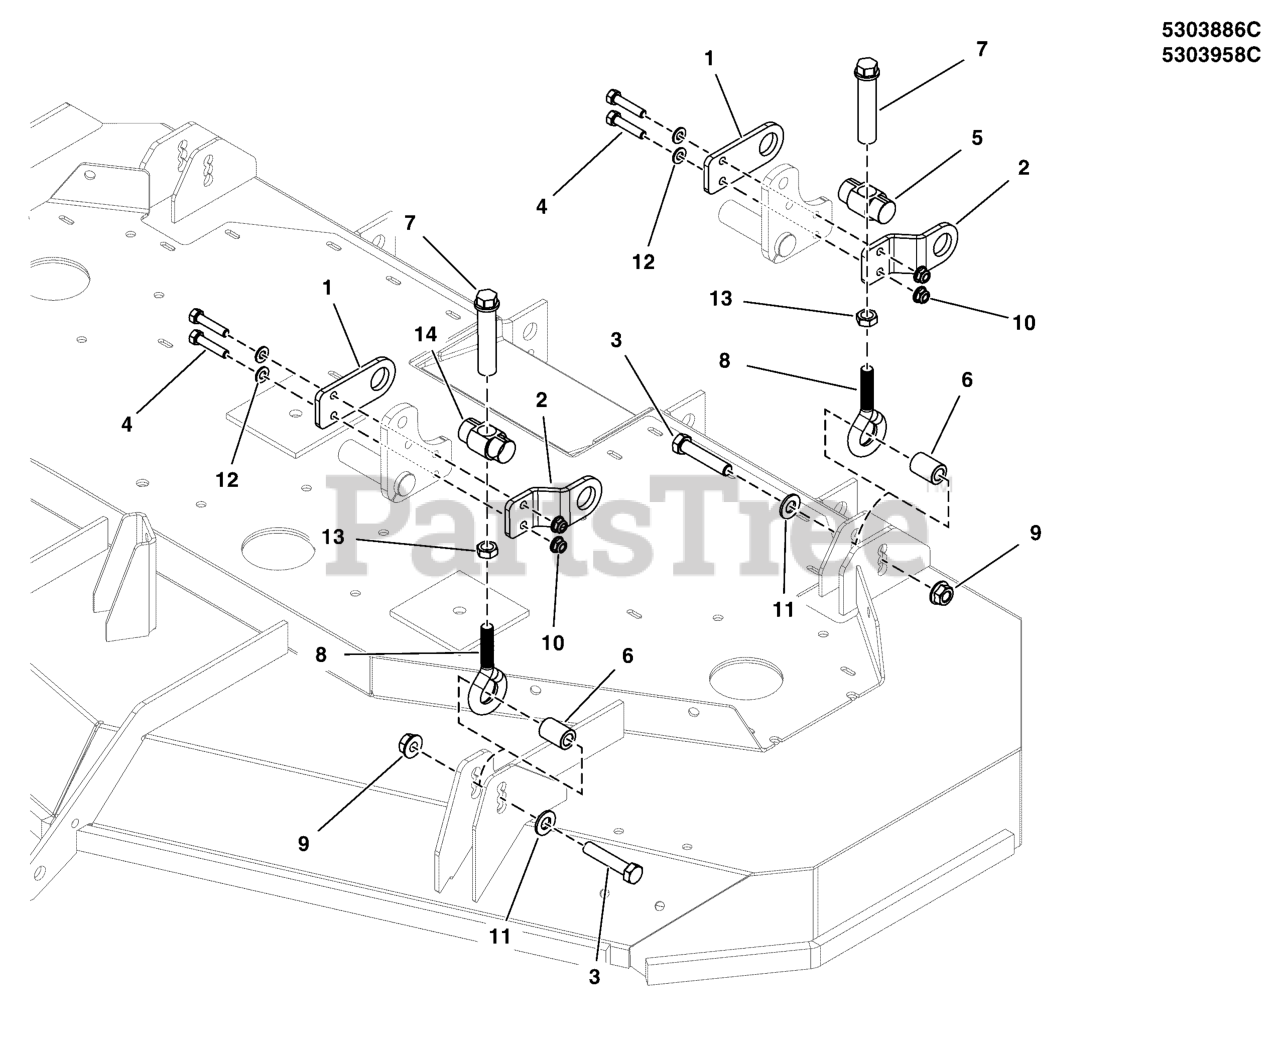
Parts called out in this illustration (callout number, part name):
3	BOLT, 1/2-13 X 2-1/2 GD5 YZ
4	CAPSCREW, Hex Head, 3/8-16 X 1-1/2
6	SPACER
7	HEIGHT ADJUST
8	EYE BOLT
9	NUT, Hex Flange, 1/2-13
10	NUT, Hex Flange, Nylock, 3/8-16
11	WASHER, 1/2
12	WASHER, .406
13	NUT, Hex Jam, 1/2-20
